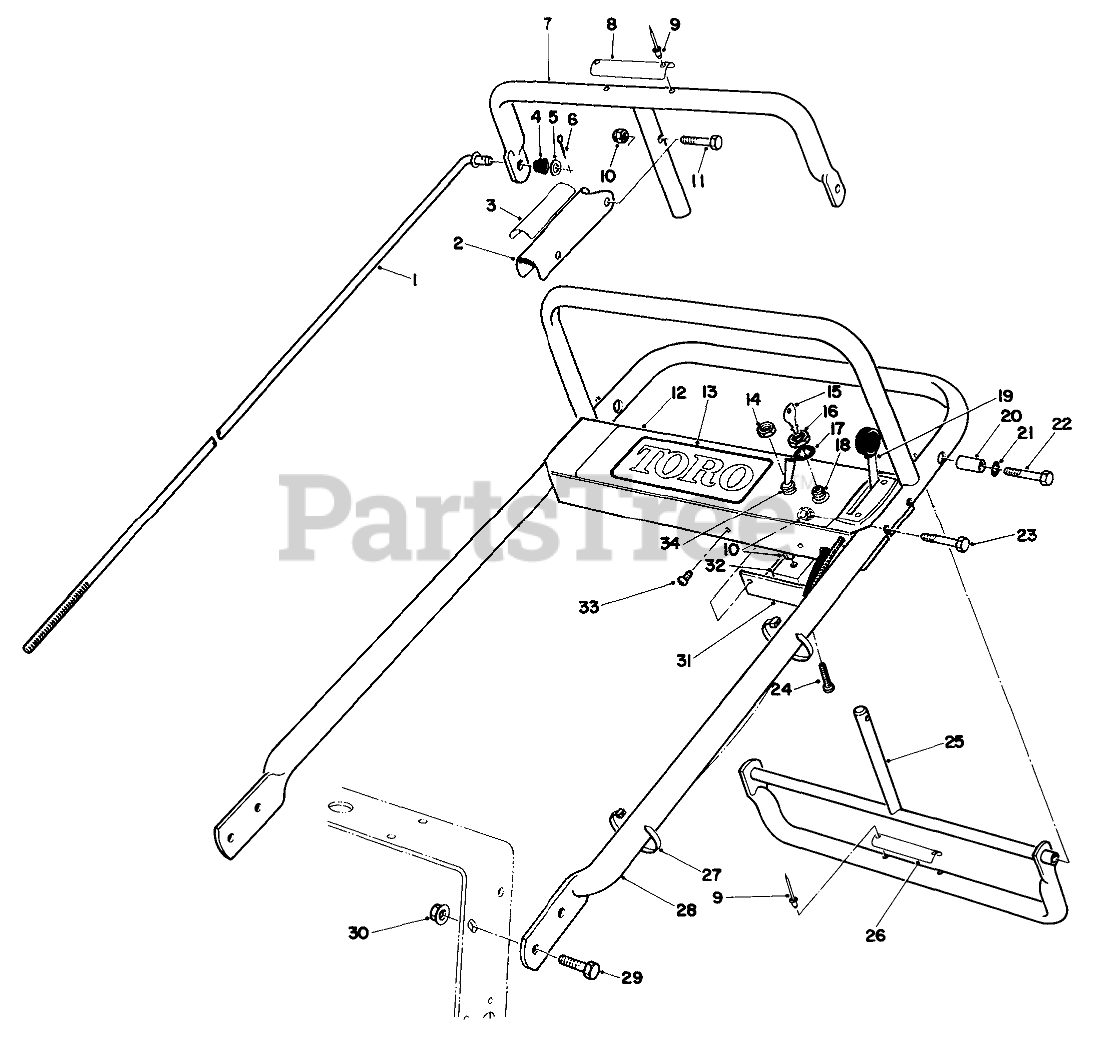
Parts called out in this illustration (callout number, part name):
1	ROD-CONTROL
2	Lever-Parking Brake
3	DECAL-LEVER, PARKING
4	GROMMET-RUBBER
5	WASHER-PLAIN
6	PIN-COTTER
7	Bar-Control
8	DECAL-CONTROL BAR
9	RIVET-BLIND
10	NUT-LOCK, NI
11	SCREW-SHH
12	Panel-Control
13	DECAL-CONTROL PANEL
14	NUT
15	Key
16	NUT-HH
17	WASHER-TOOTH, INTERNAL
18	Switch (Incl. Ref. # 18 & 19)
19	THROTTLE-CONTROL
20	PIVOT-SPACER
21	WASHER-LOCK
22	SCREW-HH
23	SCREW-SHH
24	SCREW-HWH
25	Control-Pivot
26	DECAL-REVERSE HANDLE
27	TIE-CABLE
28	HANDLE-UPPER
29	SCREW-HHF
30	NUT-HF
31	PANEL-BOTTOM
32	Bridge Rectifier
33	SCREW-HWHTF
34	Switch-Clutch (Incl. Ref. #14)
